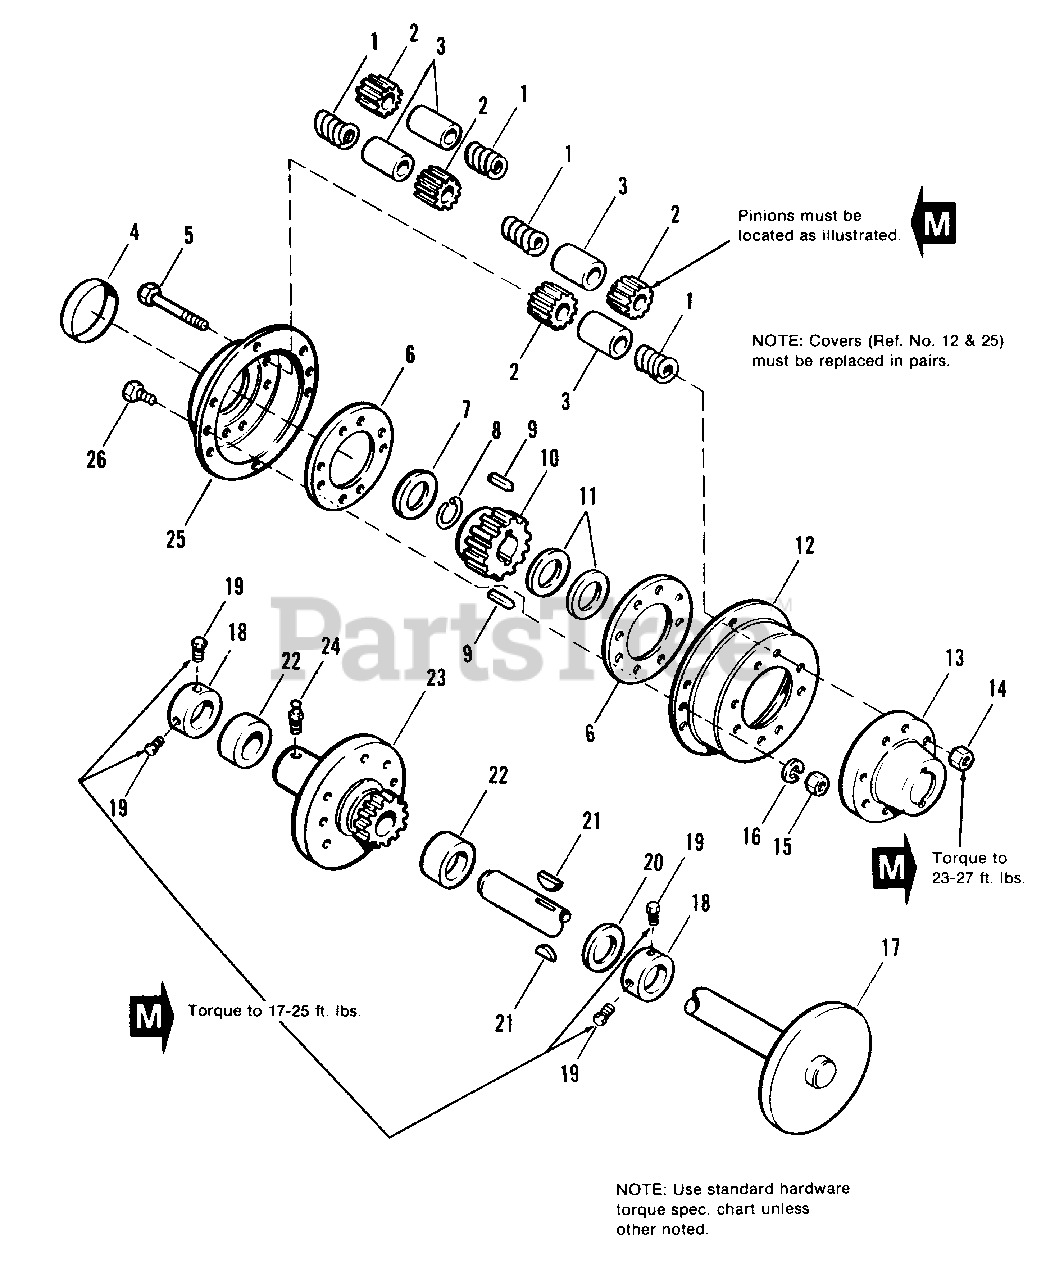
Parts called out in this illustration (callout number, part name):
1	SPRING
2	PINION, Differential
3	SPINDLE, Differential
4	SEAL, Cover
5	CAPSCREW, Hex Hd., 3/8-16 x 2-1/2
6	RING, Spacer
8	RING, Retaining
9	KEY, Hi-Pro
10	GEAR, Differential
12	COVER, Differential
13	CARRIER, Differential
14	LOCKNUT, Hex, 3/8-16
15	NUT, Hex, Full, 1/4-20
16	LOCKWASHER, 1/4
17	AXLE ASSY., Rear
18	COLLAR, Set
19	SETSCREW, 5/16-18 x 1/2
23	HUB ASSY., Wheel, RH
24	FITTING, Grease
25	COVER, Differential
26	CAPSCREW, Hex Hd., 1/4-20 x 5/8
26	DIFFERENTIAL SUB ASSY.
